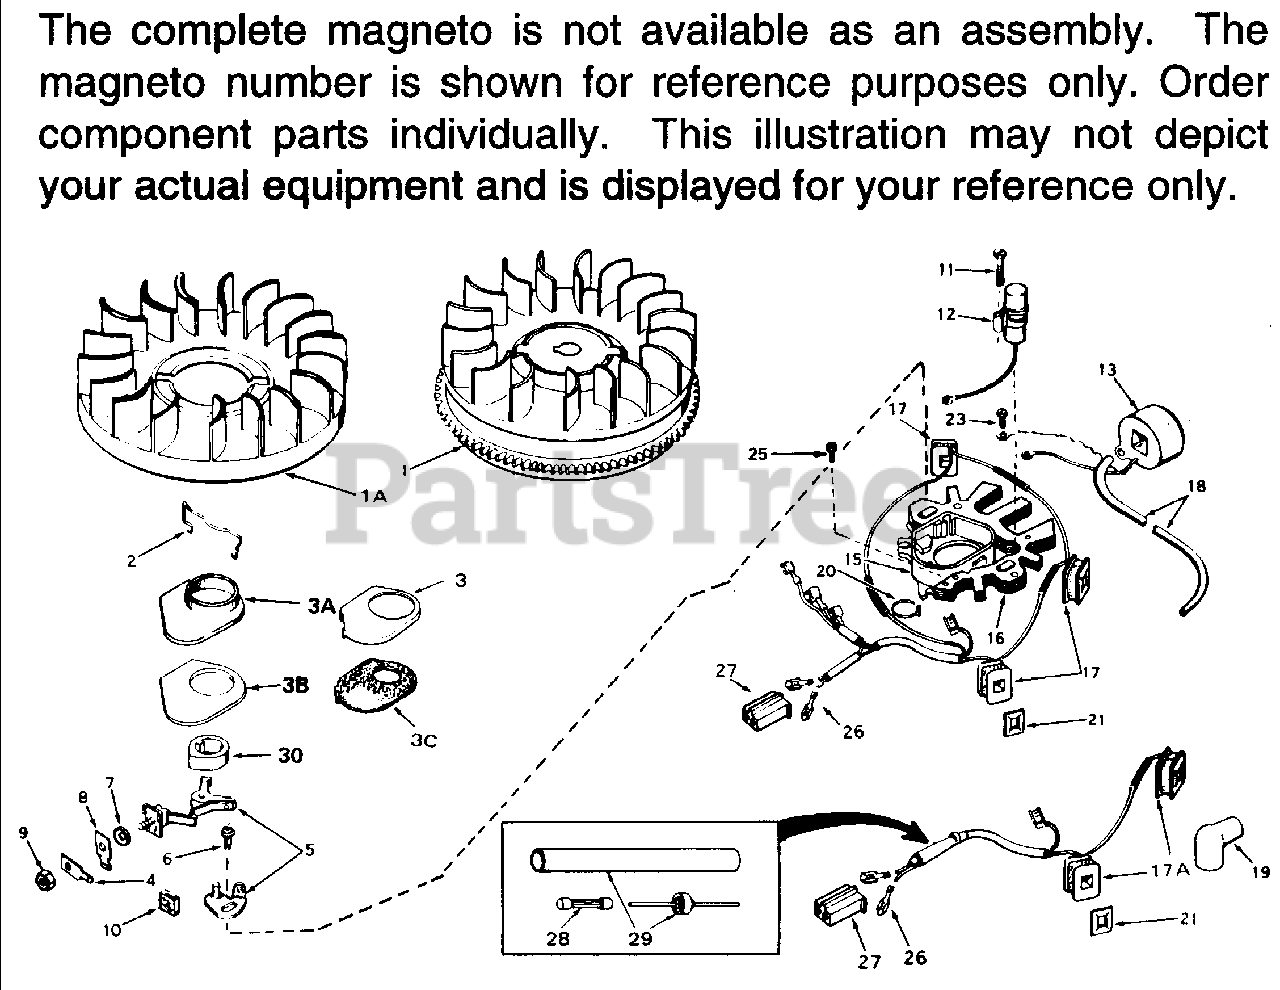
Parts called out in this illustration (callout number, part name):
1	Flywheel (Incl. 1A)
2	Spring, Dust cover
3C	Gasket, Dust cover Late style, 25/32 Hole
3C	Gasket, Dust cover Late style, 29/32 Hole
4	Terminal
5	Breaker Points (also available in Pac kaged Part #740037B)
6	Screw & Lockwasher
7	Washer, Terminal
8	Tab, Terminal
9	Nut, Terminal
10	Felt, Cam wiper
11	Screw, Condenser fastening
12	Condenser (also available in Packaged Part #740037B)
13	Coil Assy.
15	Stator Plate Assy. Incl. 2 thru 3C, 5 thru 13,16, 17A & 18 thru 25
16	Core & Plate Group
17A	Generator Coils & Leads Incl. 26,27, 28,29
18	Wire, Lead
19	Cover, Spark plug
21	Clip, Coil fastening
23	Screw, Ground terminal
25	Screw, 4-40 x 1/4"
26	Terminals
27	Connector
28	Fuse (6 Amp)
29	Diode Assy.
